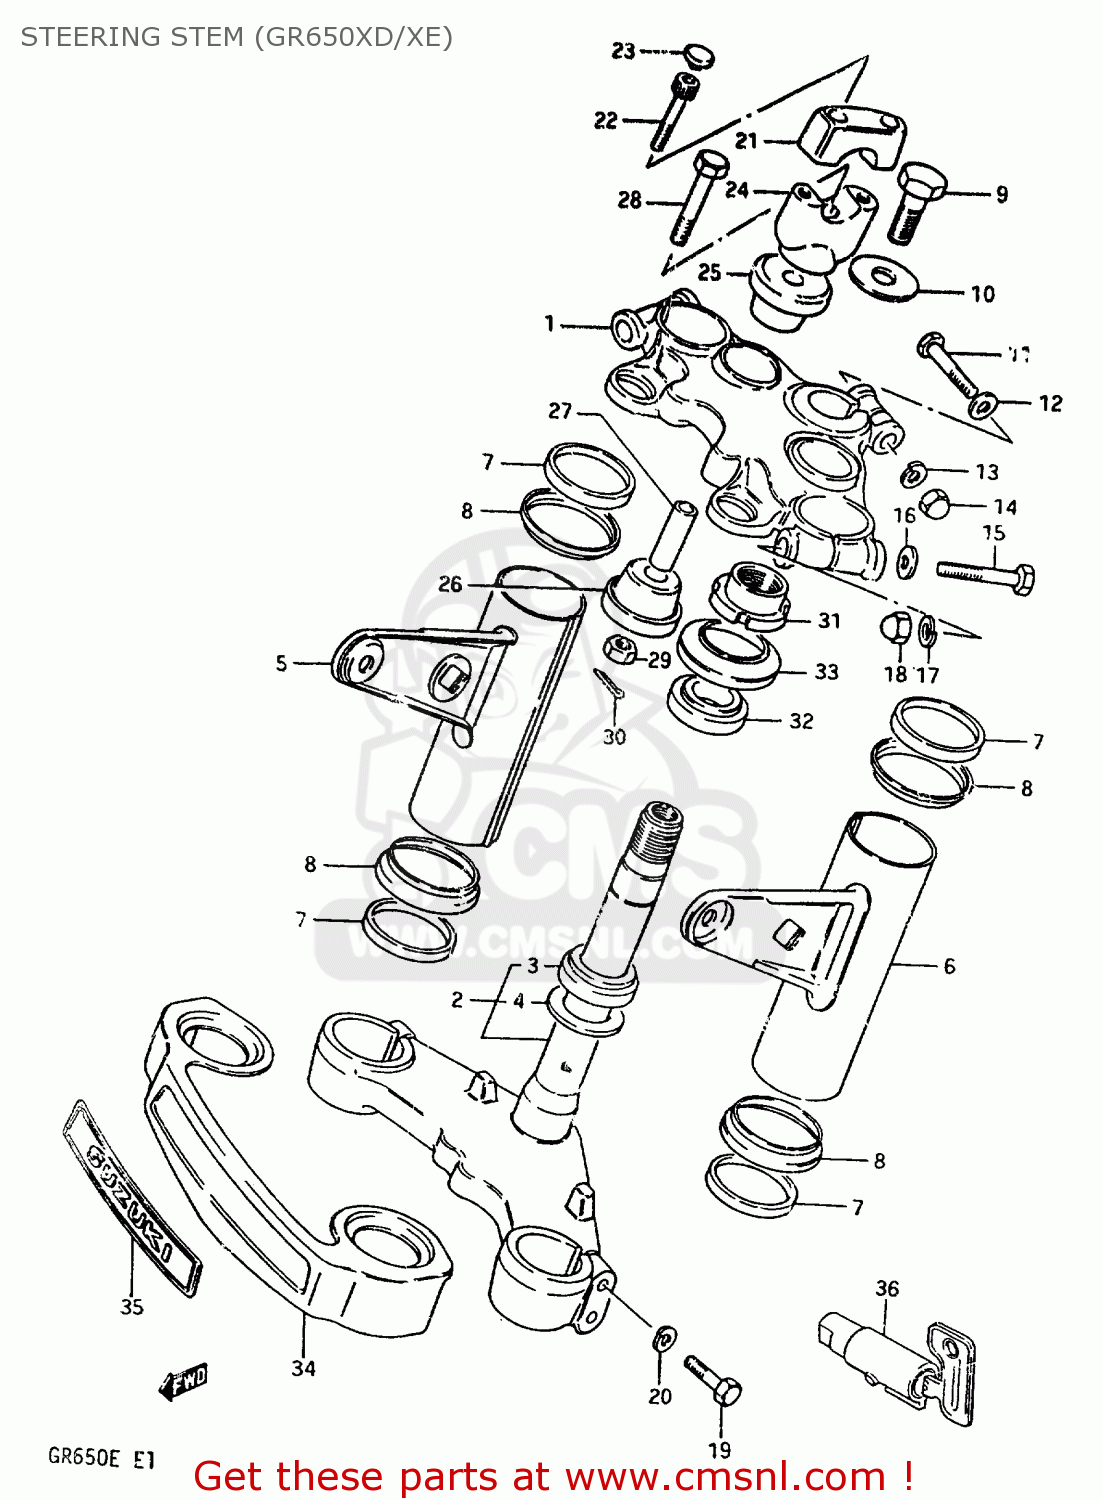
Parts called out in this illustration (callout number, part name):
1	HEAD,STEERING STEM
2	STEM,STEERING
3	BEARING
4	WASHER,THRUST
5	BRACKET COMP,HEADLAMP
6	BRACKET,HEADLAMP,LEFT
7	CUSHION,HEADLAMP BRACKET
8	CAP,HEADLAMP BRACKET
9	BOLT,STEERING STEM HEAD
10	WASHER
11	BOLT 8X50
12	WASHER
13	LOCK WASHER
14	NUT,M8X1.25X12
15	BOLT 10X55
16	WASHER 10MM
17	LOCK WASHER
18	NUT
19	BOLT 8X40
20	LOCK WASHER
21	CLAMP,HANDLE BAR,UPPER
22	BOLT
23	CAP(OD:14.5)
24	CLAMP,HANDLE BAR,LOWER
25	CUSHION,LWR
26	CUSHION,LWR
27	SPACER(10.2X14X46)
28	BOLT(10X78)
29	NUT
30	COTTER PIN
31	NUT,STEERING STEM
32	TAPER,ROLLER BEARING
33	DUST SEAL,STEERING UPR
34	COVER, FRONT FORK
35	EMBLEM,FRONT FORK COVER
36	LOCK ASSEMBLY,STEERING (NEI
